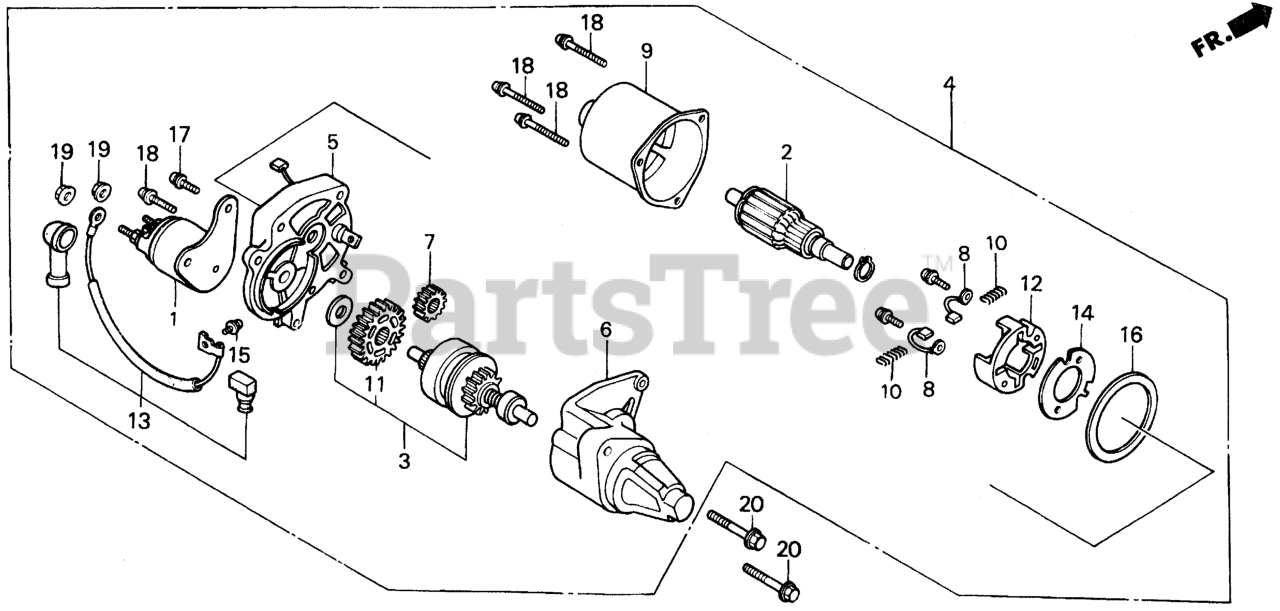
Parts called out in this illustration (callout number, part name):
1	CONTACTOR ASSY.
2	ARMATURE
3	CLUTCH, OVERRUNNING
4	STARTER MOTOR UNIT
5	BRACKET, CENTER
6	BRACKET, FR.
7	GEAR, DRIVE PINION
8	BRUSH
9	YOKE
10	SPRING, BRUSH RETURN
11	GEAR, REDUCTION
12	HOLDER, BRUSH
13	WIRE, WATER COVER
14	INSULATOR
15	SCREW-WASHER (4X6)
16	GASKET
17	SCREW-WASHER (5X14)
18	SCREW-WASHER (5X3)
19	NUT-WASHER (6MM)
20	BOLT, FLANGE (8X35)
